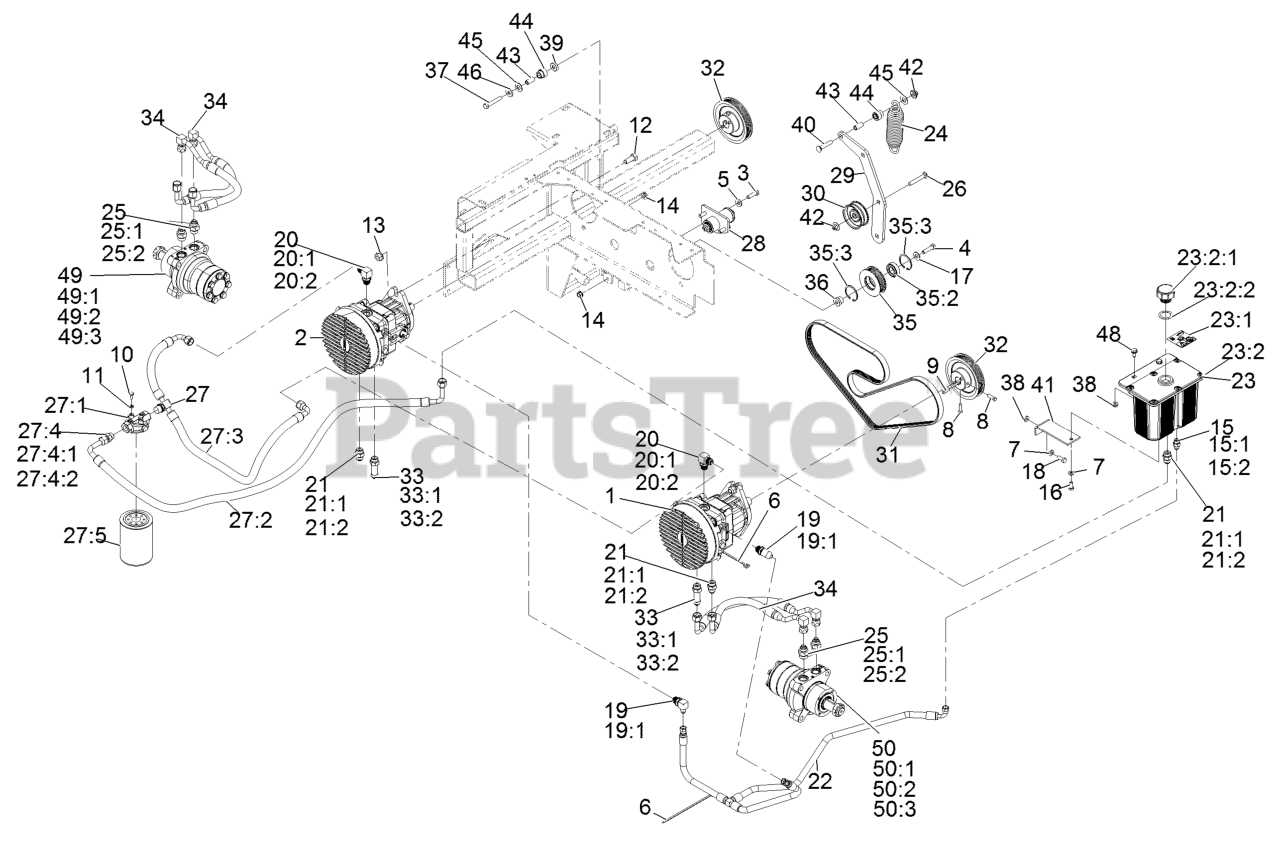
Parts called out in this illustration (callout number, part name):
1	PUMP, LH
2	PUMP, RH
3	SCREW-HH
4	SCREW-HH
5	WASHER-BELLEVILLE
6	TIE-PLASTIC
7	WASHER-PLAIN
8	SCREW-SET
10	SCREW-HH
11	WASHER-LOCK
12	SCREW-HH
13	NUT-HHF
14	NUT-HHF, WHIZ
15	FITTING-STRAIGHT
16	SCREW-HH
17	WASHER-FLAT
18	SCREW-HH
19	FITTING-ELBOW, 90 DEG
20	FITTING-90 DEG
21	FITTING-STRAIGHT
22	ASM,CASE DRAIN HOSE
23	HYDRAULIC TANK ASM
23:1	DECAL-WARNING
23:2	Tank-Hydraulic
23:2:1	Cap-Reservoir, HYD
23:2:2	GASKET-CAP
24	SPRING-EXTENSION
25	FITTING-STRAIGHT
25:1	O-RING
26	SCREW-CARR
27	Asm, Charge Hose
27:1	HEAD-FILTER
27:2	ASM, HOSE-FILTER INLET
27:3	ASM, HOSE-PUMP INLET
27:4	FITTING-STRAIGHT
27:5	FILTER,XP HYD 25 MICRON
28	KIT,PUMP IDLER
29	ARM,PUMP IDLER
30	IDLER,FLANGED
31	BELT, 5K 68.8
32	SHEAVE,5K 5.0" PD POLY-V
33	ADAPTER-STR, LONG
33:1	O-RING
34	HYD HOSE ASM
35	ASM,LOWER FRAME IDLER
35:2	BEARING-BALL
35:3	RING-RETAINING
36	SPACER,LOWER FRAME IDLER
37	SCREW-HH
39	SPACER-BRACKET, GUIDE
40	SCREW-HH
41	BRACKET, HYDRAULIC TANK
42	Nut-Nyloc 3/8-16 Flg
44	BUSHING,PLASTIC
45	WASHER-TEFLON
46	WASHER
48	Screw-HWH 5/16-18 X 3/4 Tf
49	HYD MOTOR ASM (CW)
49:1	KEY-WOODRUFF
50	HYD MOTOR ASM (CCW)
50:1	KEY-WOODRUFF
